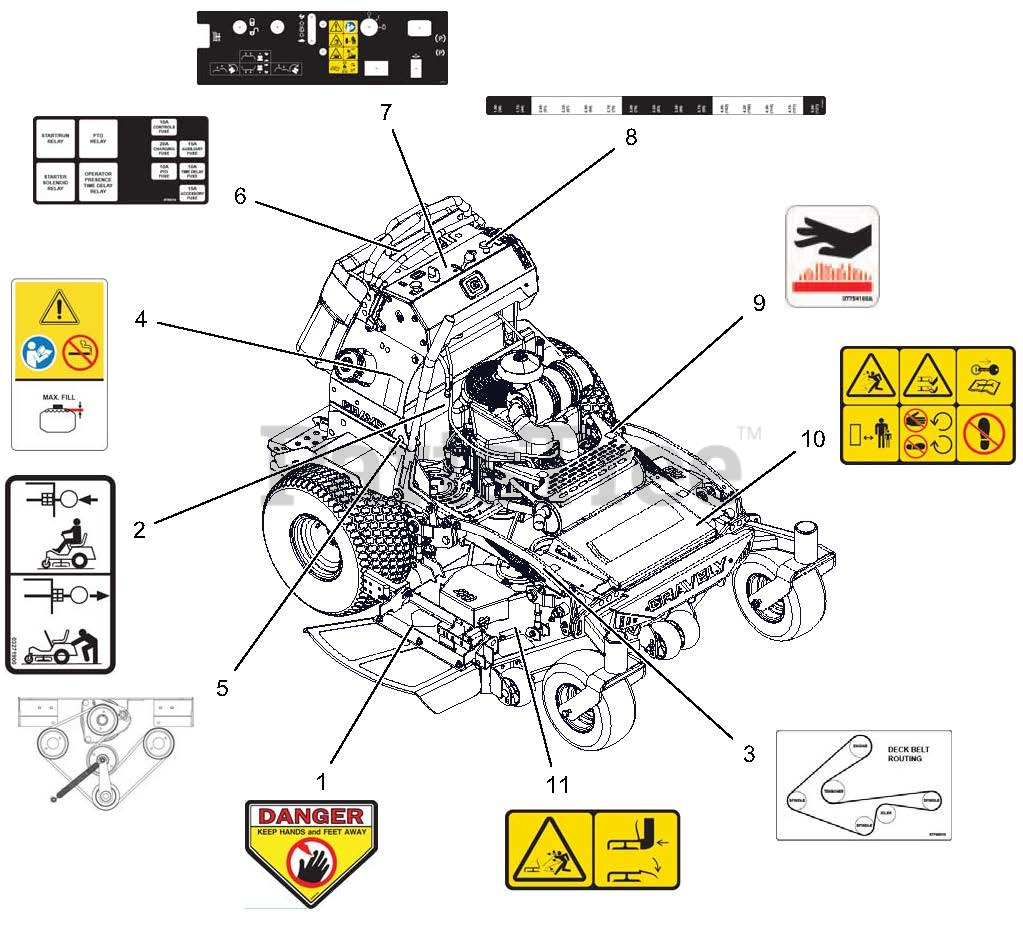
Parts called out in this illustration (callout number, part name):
1	DECAL, DANGER
2	DECAL, TRANSMISSION DISCONNECT
3	DECAL, BELT ROUTING 48/52
4	DECAL, FUEL WARNING
5	DECAL, PROSTANCE HYD BELT ROUT
6	DECAL, FUSE BLOCK
7	DECAL, PS CONTROL PANEL
8	DECAL, 48-60 PS HOC DIAL
9	DECAL, HOT SURFACE
10	DECAL, SAFETY - MOWER DECK
11	DECAL, SAFETY - DECK GUARDING
